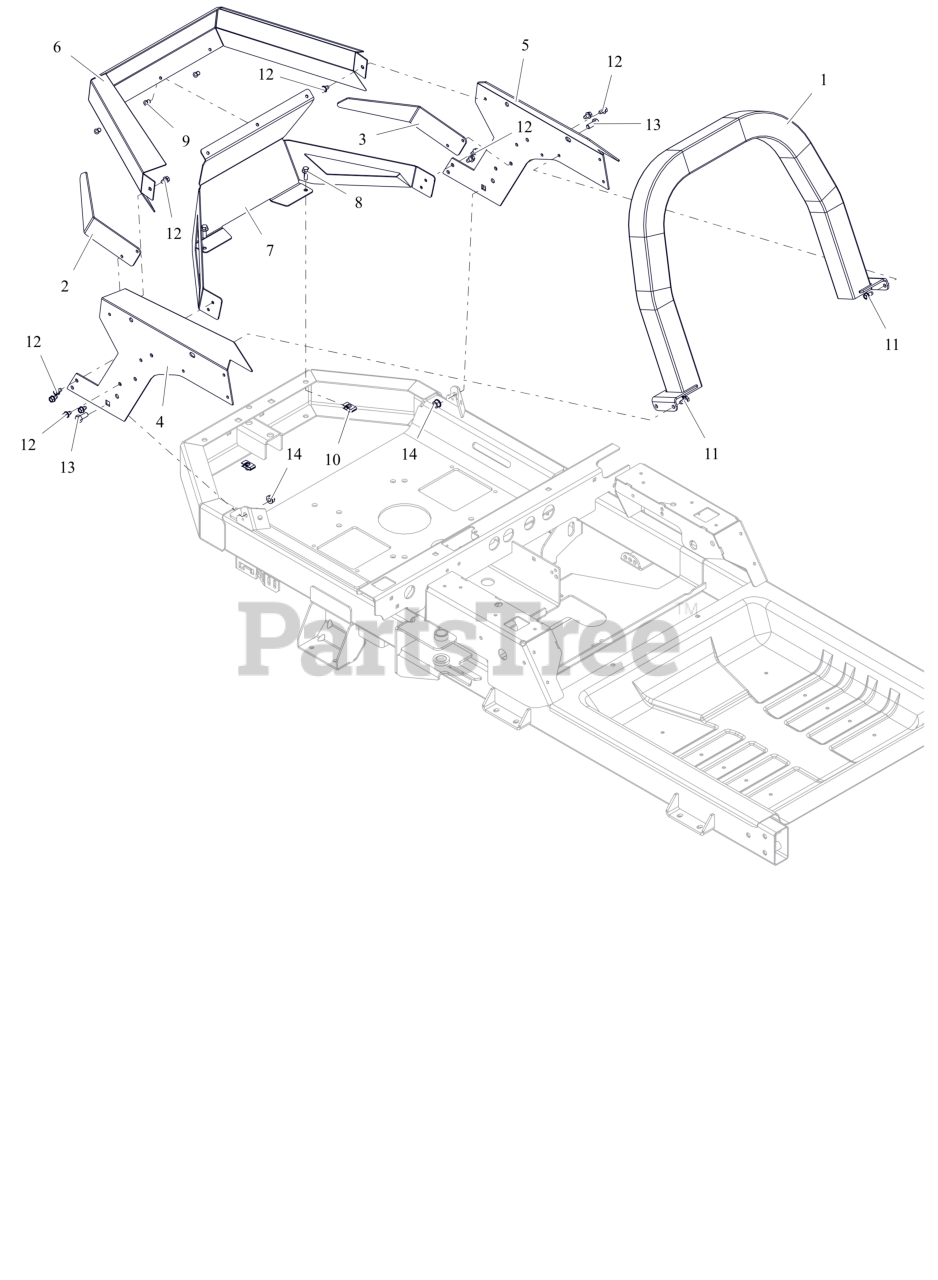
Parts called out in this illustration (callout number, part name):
1	WLDMT, ENGINE-TOP GUARD (ORANGE)
2	SHIELD, RH, ENGINE GUARD VALVE
3	SHIELD, LH, ENGINE GUARD VALVE
4	PANEL, RIGHT REAR FENDER MOUNT (ORANGE)
5	PANEL, LH REAR FENDER MOUNT (ORANGE)
6	GUARD, ENGINE WRAP (ORANGE)
7	GUARD, ENGINE -BOTTOM (BLACK)
8	BLT,HEX-FLG .25-20X.75 G5 BFP
9	RIVET, #66 STEEL POP PD BLACK
10	NUT-RTNR .25-20X.56
11	SCR-TAP .25-20X.50 HWH ZCC
12	SCR,TAP .25-20X.375 HWH TR ZCC
13	BLT,HEX .31-18X.75 G5 ZCC
14	NUT-LK-TOP-FLG .312-18 GF ZCC
